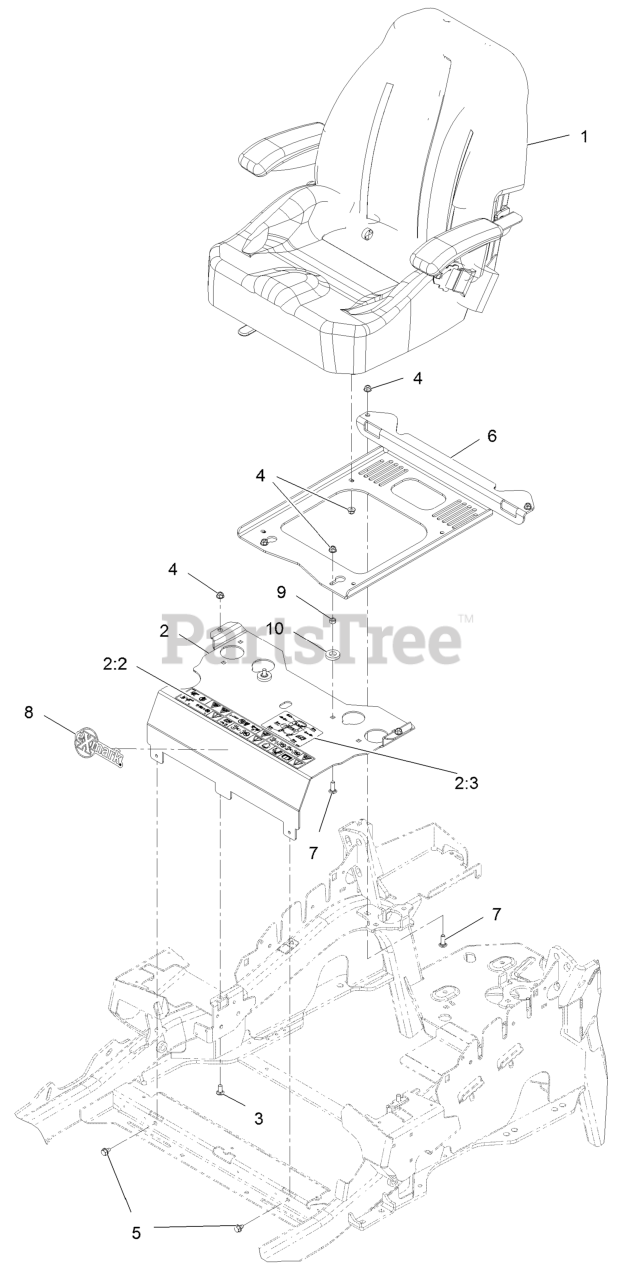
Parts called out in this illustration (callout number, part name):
1	ASM-SEAT LZE
2	MOUNT-SEAT
2:2	DECAL-CONSOLE
2:3	DECAL-SERVICE AID
3	SCREW-CARR
4	NUT-HF, NI
6	PLATE-SUPPORT, SEAT
7	SCREW-CARR
9	NUT-HEX
